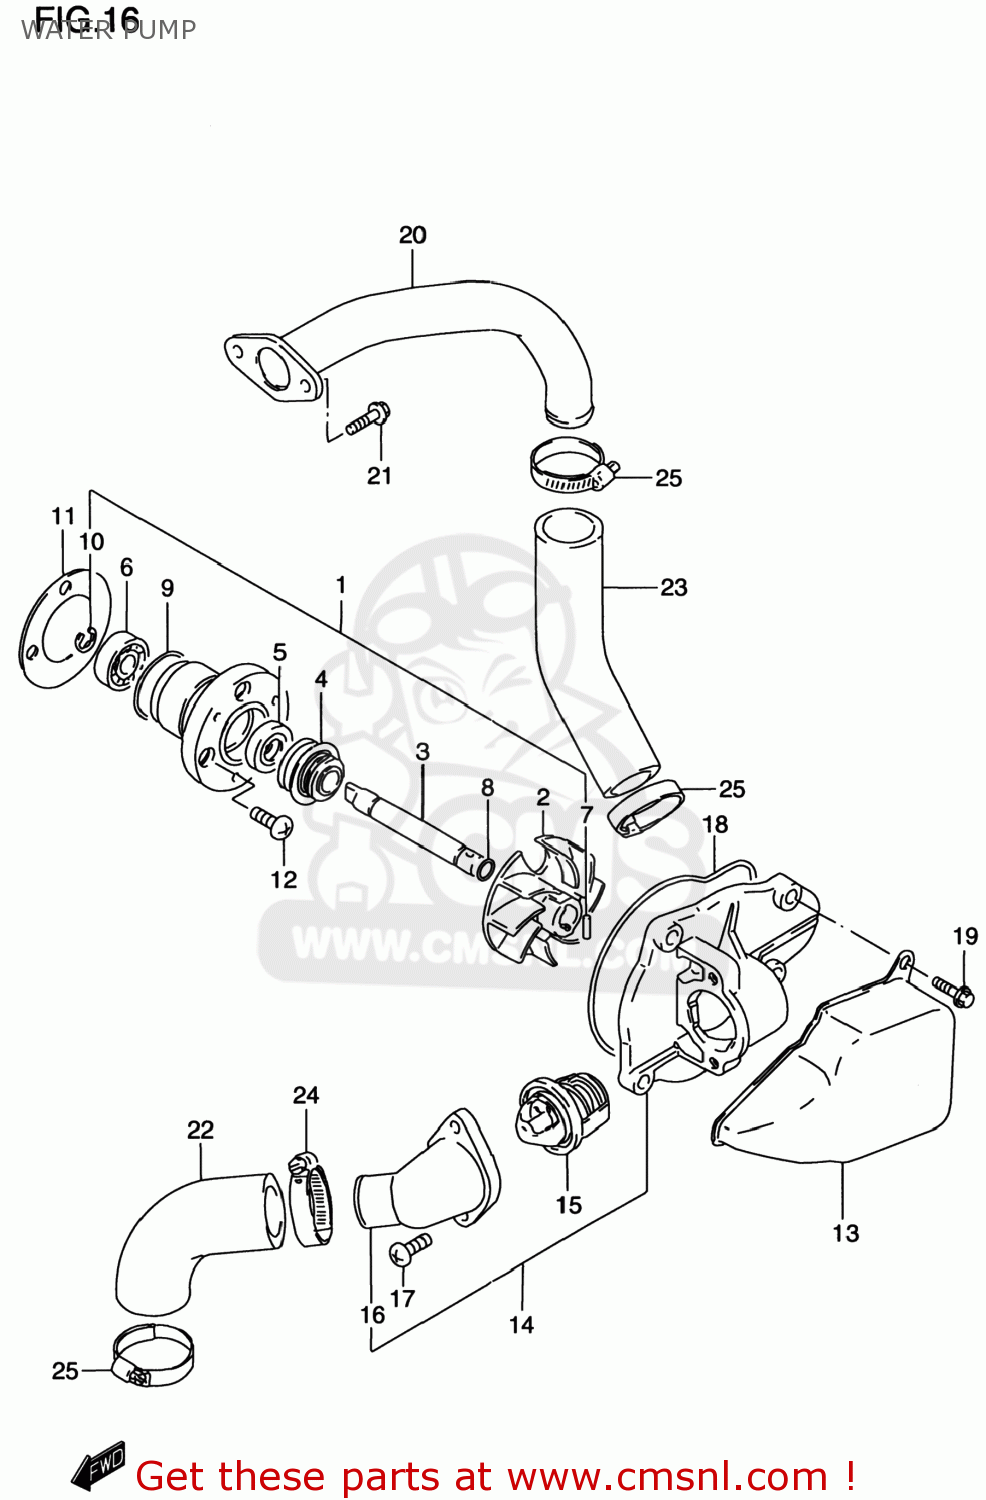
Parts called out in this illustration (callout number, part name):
1	PUMP ASSEMBLY,WATER
2	IMPELLER
3	SHAFT
4	SEAL,MECHANICAL
5	SEAL,OIL(10X21X5)
6	BEARING(10X22X6)
7	PIN
8	O RING
9	O RING
10	E RING
11	GASKET,WATER PUMP (NAS)
12	SCREW
13	COVER,WATER PUMP
14	CASE ASSY,WATER PUMP
15	THERMOSTAT,WATER
16	CONNECTOR
17	SCREW
18	O RING,WATER PUMP CAP
19	BOLT
20	PIPE,CYLINDER INLET
21	BOLT
22	HOSE,WATER PUMP IN
23	HOSE,WATER PUMP OUTLET
24	CLAMP
25	CLAMP
